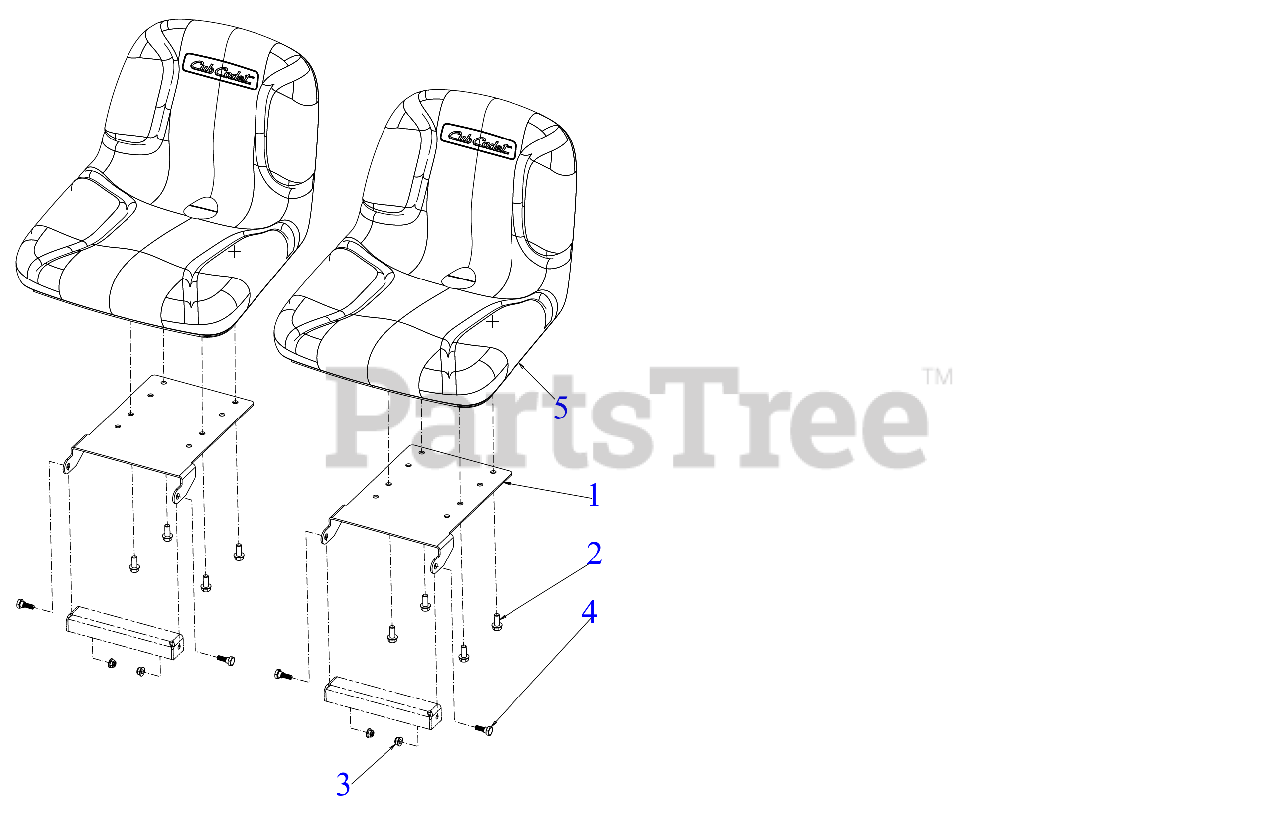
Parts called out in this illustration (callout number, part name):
2	SCREW 3/8-16 x .875 GR5
3	FLANGE LOCK NUT 5/16-18
4	SHOULDER SCREW .437 DIA x .265
5	HIGH BACK SEAT (CUB)
